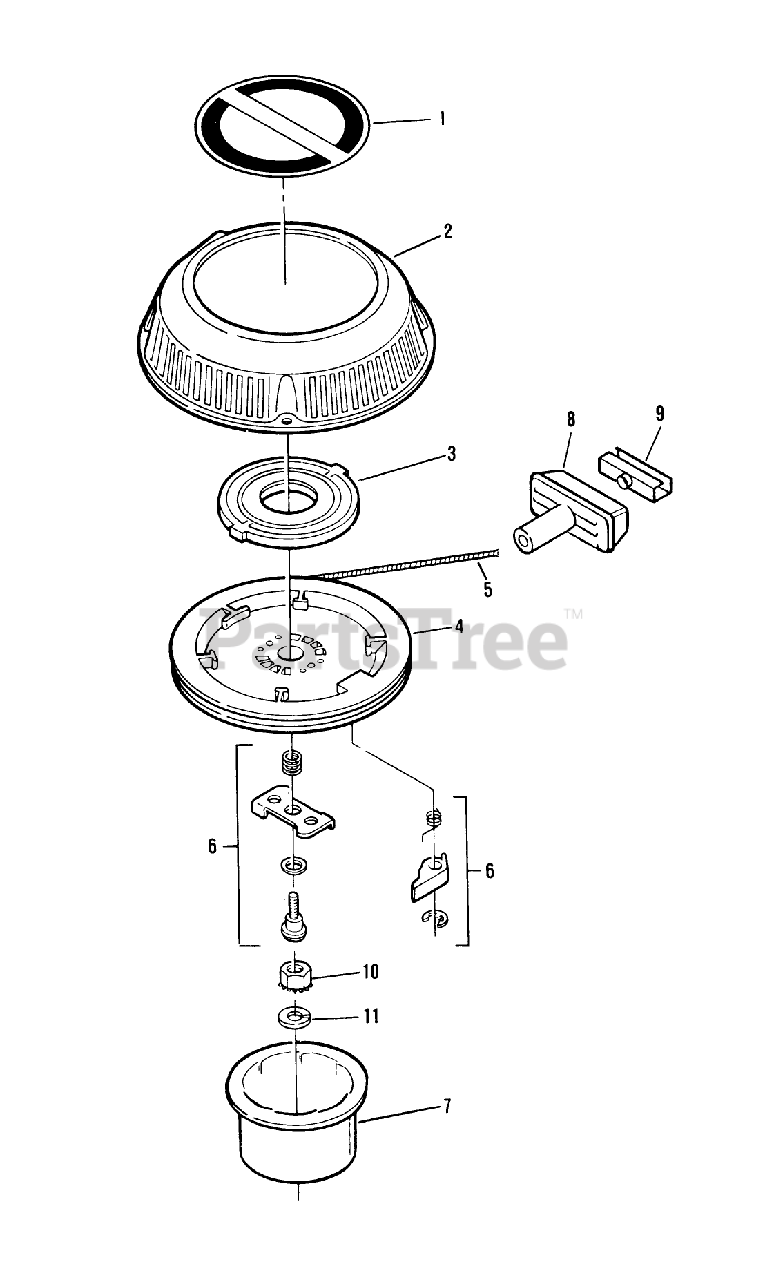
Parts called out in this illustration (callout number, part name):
6	DOG KIT AY.
7	HUB STARTER SM
9	CLIP-STARTER
10	NUT
